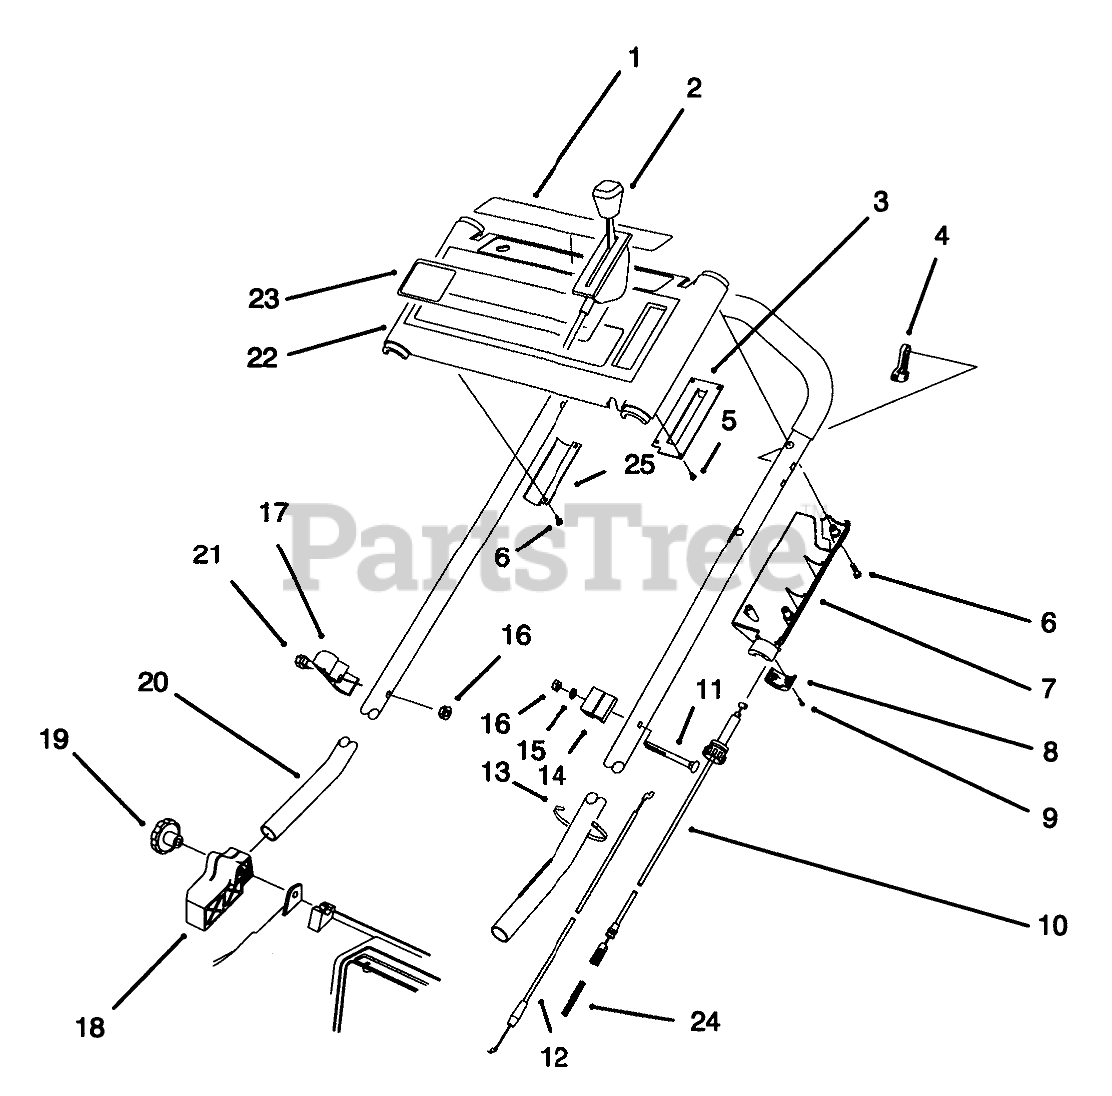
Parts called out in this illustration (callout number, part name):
1	DECAL - INSTRUCTION
2	CONTROL - THROTTLE
3	THROTTLE PLATE
4	LEVER-TRACTION
5	#6-19X.25 PLASK FORM SC
6	SCREW-PPH, PLASTITE
7	COVER-THROTTLE, LEVER
8	LOWER THROTTLE CAP
9	#4-14X.62 PLASTITE SCW
10	CABLE - TRACTION
11	SCREW-HANDLE
12	CABLE - BRAKE
13	TIE-CABLE
14	SUPPORT-CABLE
15	WASHER-FLAT
16	NUT-LOCK, NI
17	GUIDE - ROPE
18	MOUNT-HANDLE, RH
20	HANDLE (DIPPED)
21	.250-20X1.625 HH SCREW
22	Panel-Control (Incl. Ref. #1 & 23)
23	DECAL - PANEL 4-CYCLE
24	SPRING-COMPRESSION
25	Bracket-Panel
